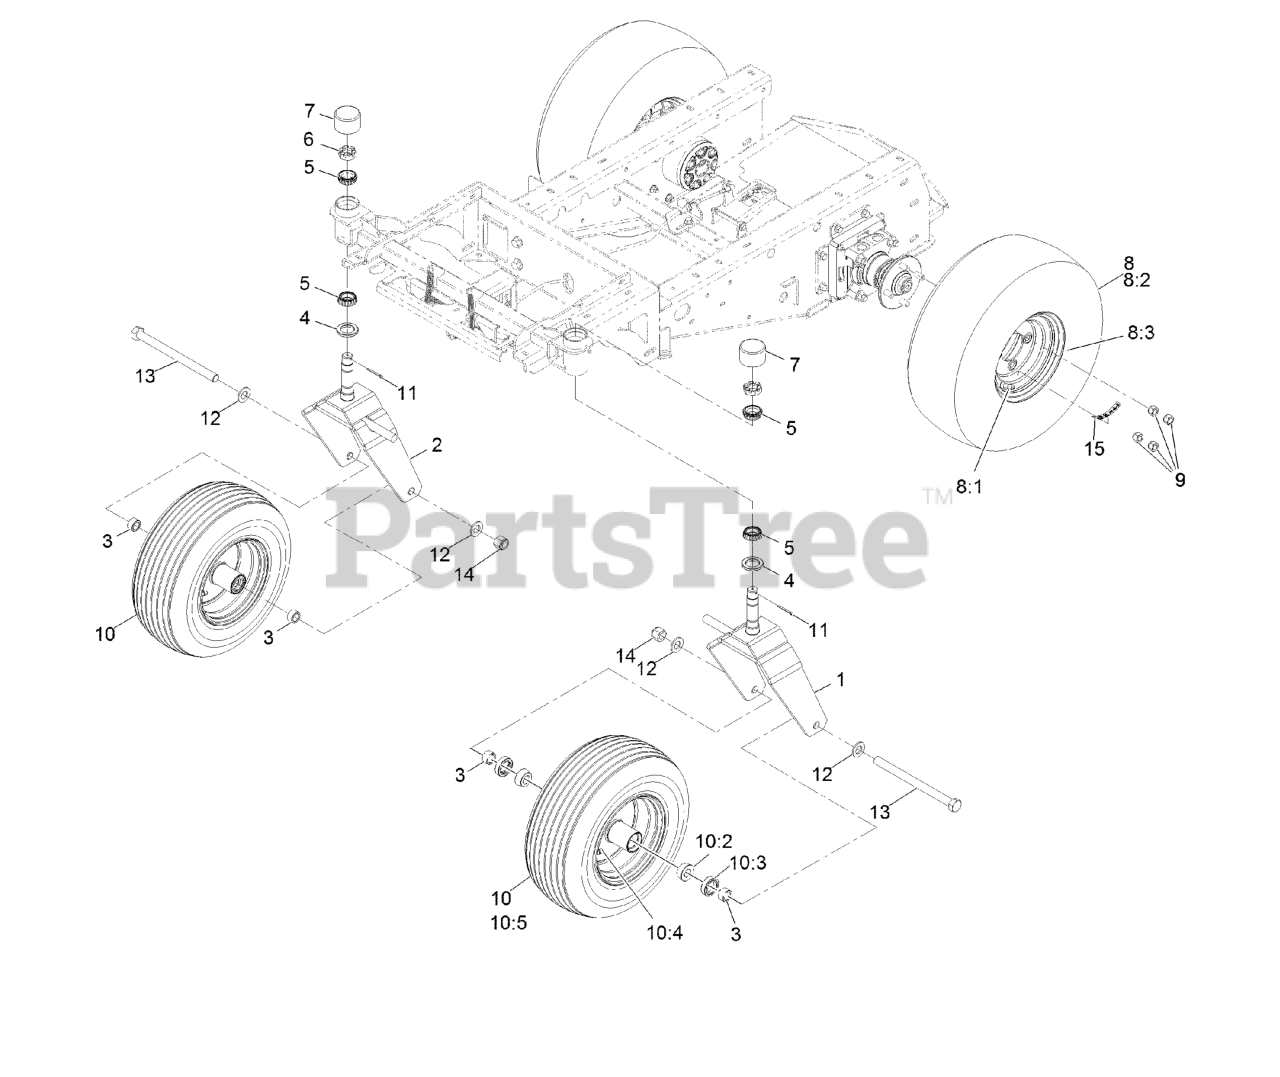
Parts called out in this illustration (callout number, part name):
1	Caster-Lt [black]
2	Caster-Rt [black]
3	SPACER-AXLE
4	SEAL-GREASE
5	CONE-BEARING, OUTER
6	NUT-SHH
7	CAP-DUST, RUBBER
8	WHEEL AND TIRE ASM
8:1	Rim-8 X 5.38, Black
8:2	Tire- 20 X 8 4 Ply
8:3	Stem-Valve
9	NUT-LUG
10	WHEEL AND TIRE
10:2	BEARING-CONE, TAPERED ROLLER
10:3	SEAL-CASTER
10:4	VALVE
10:5	Tire-Rib
11	Pin-Cotter
12	WASHER-FLAT
13	SCREW-HH
14	NUT-LOCK, NI
15	DECAL-TORQUE, WHEEL HUB LUG
